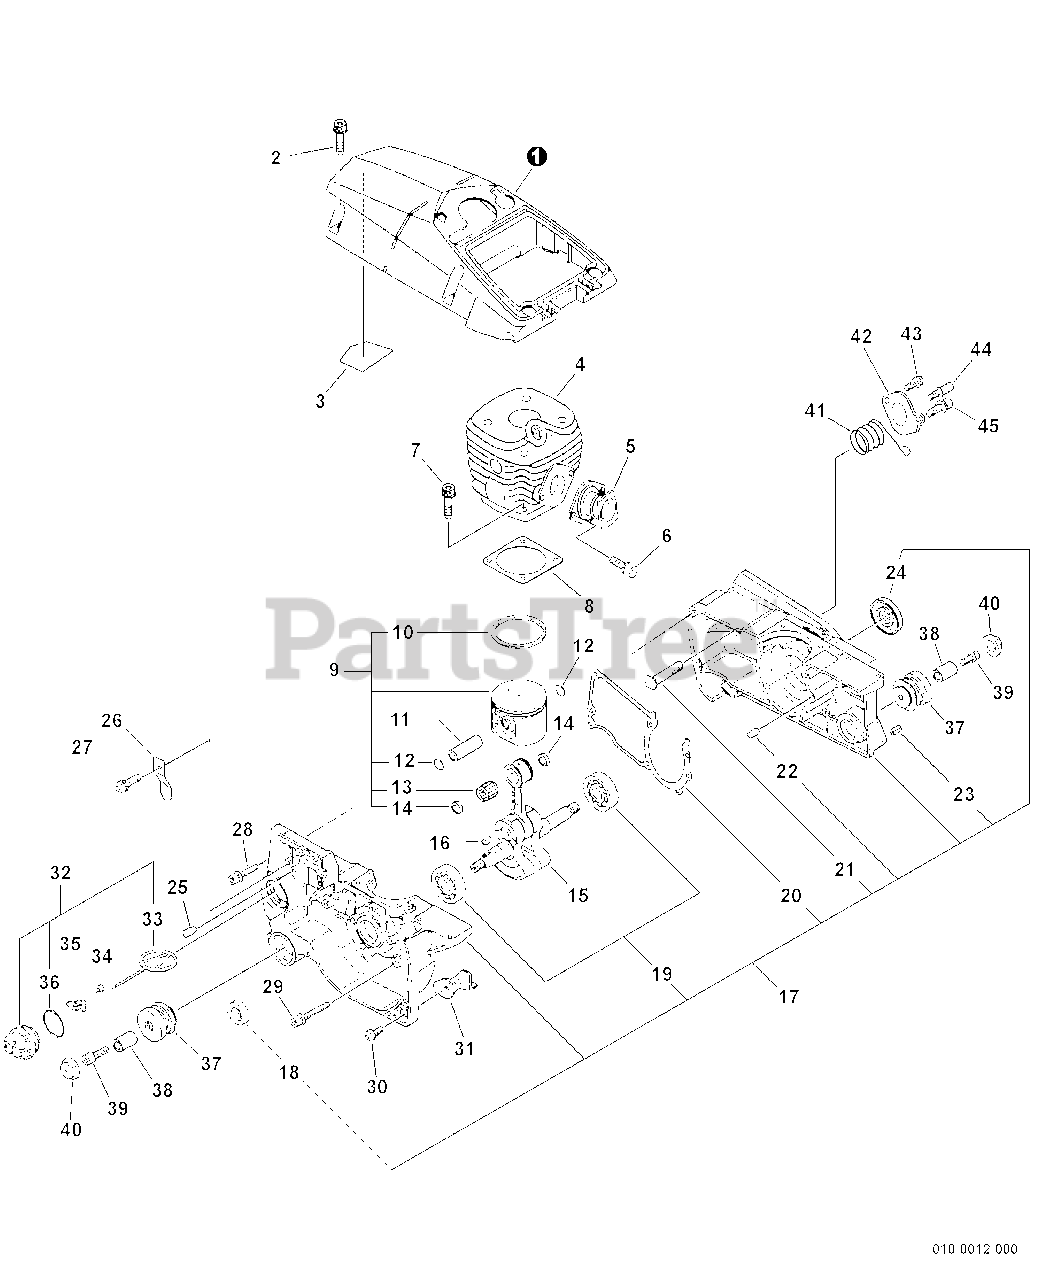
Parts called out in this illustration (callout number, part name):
1	COVER, ENGINE
2	SCREW - 5X20
3	DEFLECTOR, HEAT
4	CYLINDER
5	BELLOWS, INTAKE
6	SCREW - 5X14
7	SCREW - 5X25
8	GASKET, CYLINDER
9	PISTON KIT
10	RING, PISTON
11	PIN, PISTON
12	RING, RETAINING
13	BEARING, NEEDLE
14	SPACER, PISTON
15	CRANKSHAFT ASSY
17	CRANKCASE KIT
18	SEAL, OIL
19	BEARING, BALL - 6202
20	GASKET, CRANKCASE
21	STUD, GUIDE BAR
22	PIN - LOCATING
23	PIN - SPRING -- 5X10
24	SEAL, OIL
25	VENT, TANK
27	SCREW - 4X8
28	SCREW - 5X20
29	SCREW - 5X35
30	SCREW - 5X14
32	CAP ASSY
33	CONNECTOR, CAP
34	SCREW - 3X8
35	RETAINER
36	O-RING - 25
37	CUSHION
38	COLLAR - 5
39	SCREW - 5X25
40	CAP, CUSHION
43	SCREW - 4X8
44	STUD, THREADED
45	SCREW - 5X14
